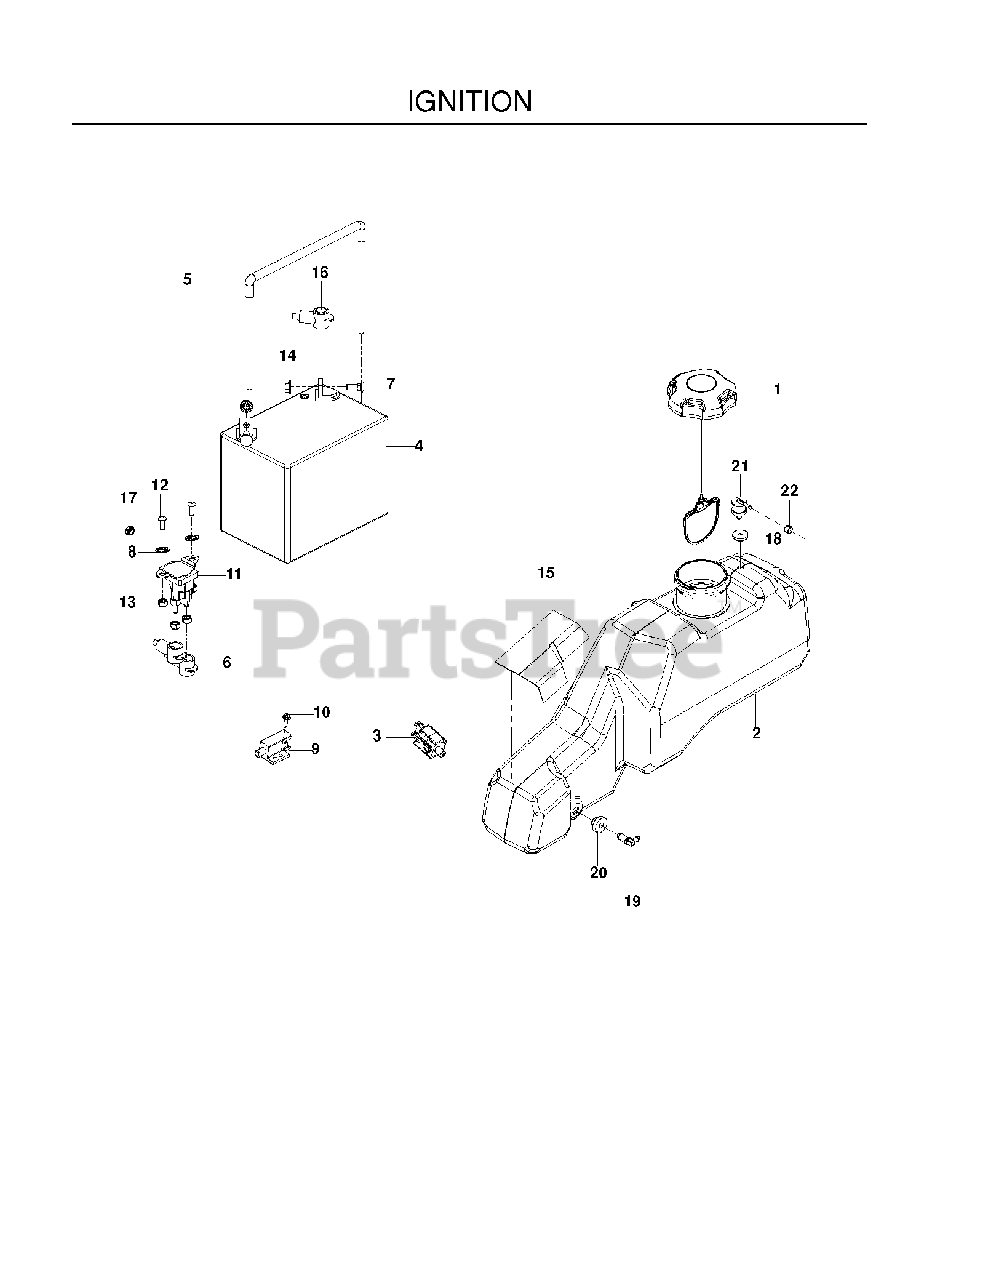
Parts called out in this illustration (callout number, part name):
1	CAP, FUEL
2	TANK, FUEL, RT-EPA
3	SWITCH, BRAKE 3P
4	BATTERY, 12 V 330 AMP TBR
5	BATTERY TIE DOWN ASSEMBLY
6	TERMINAL COVER-SM
7	BOLT 5/16C X 3/4" CARRIAGE
8	WASHER 1/4 INT TOOTH
9	SWITCH, INTERLOCK
10	SCREW #10 X 1/2 SELF TAPPING
11	SOLENOID
12	SCR 1/4-20 X 5/8 BTN SKT HD ZD
13	NUT 1/4-20 NYLOC
14	5/16-18 NYLOC FLANGE NUT
15	SHIELD, HEAT
16	INSULATOR
17	JAM NUT 1/4C
18	GROMMET, CHECK VALVE
19	STEM, FUEL TANK
20	RUBBER GROMMET
21	VALVE.FUEL.CHECK
22	CLAMP, HOSE
